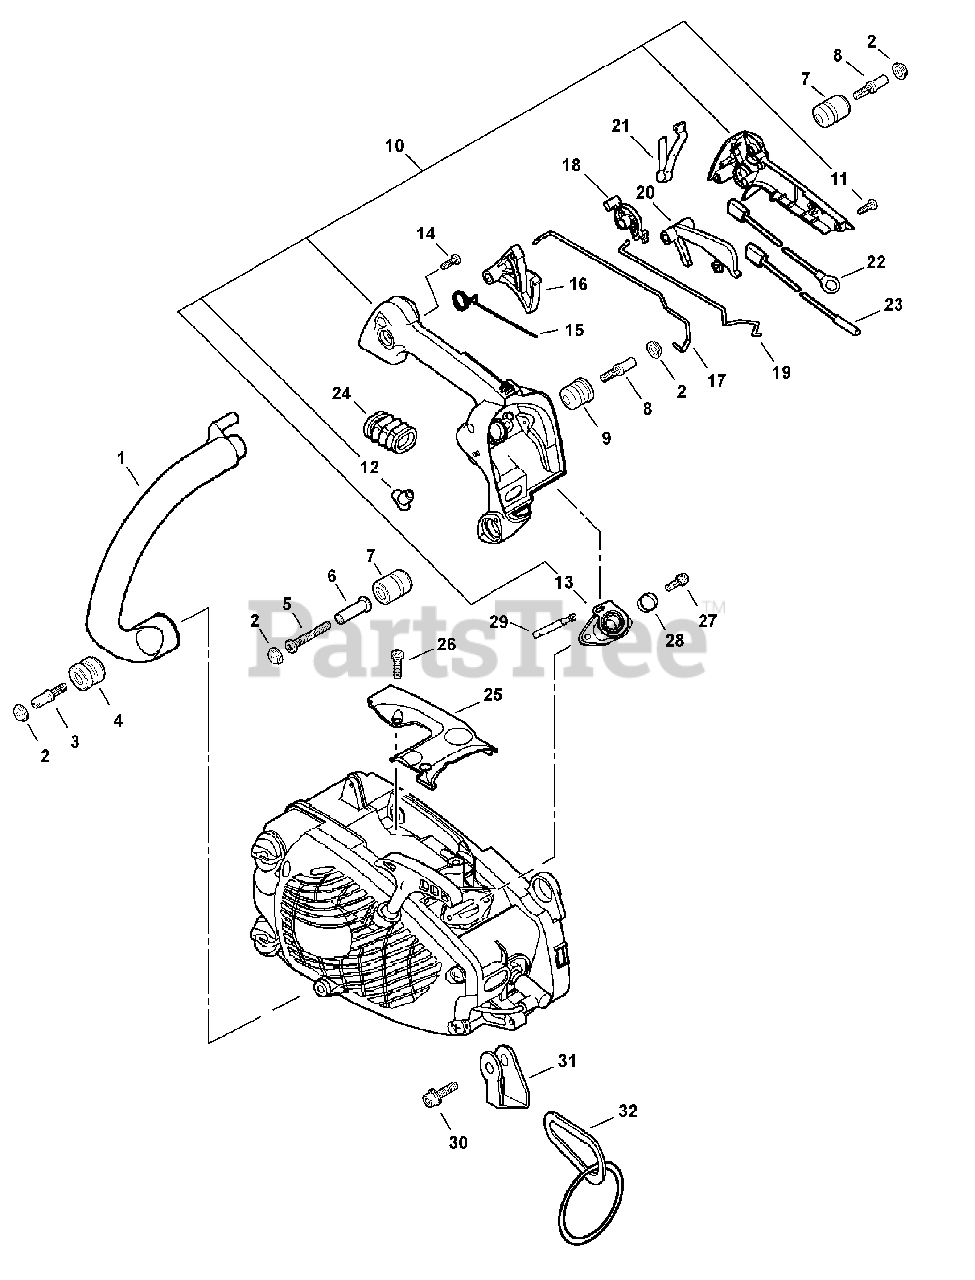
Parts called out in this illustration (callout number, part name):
1	HANDLE, FRONT
2	CAP, CUSHION
4	CUSHION 5
5	SCREW, TAPPING 4×35
6	COLLAR 4
7	CUSHION
8	BOLT 4×15
9	CUSHION 4
10	HANDLE ASSY, REAR
11	SCREW 4×16
13	BELLOWS, INTAKE
14	SCREW, TAPPING 5×20
15	SPRING, TORSION
16	TRIGGER, THROTTLE
17	ROD, THROTTLE
18	LEVER, THROTTLE
19	ROD, CHOKE
20	LOCKOUT, THROTTLE
21	TERMINAL, LEAD
24	BELLOWS, INTAKE
25	COVER, DUST
26	SCREW 4×12
27	SCREW 5×12
28	COLLAR 16
29	PIPE, PULSE 3×7×65
30	BOLT 4×25
31	BRACKET, HARNESS
32	RING, HARNESS
